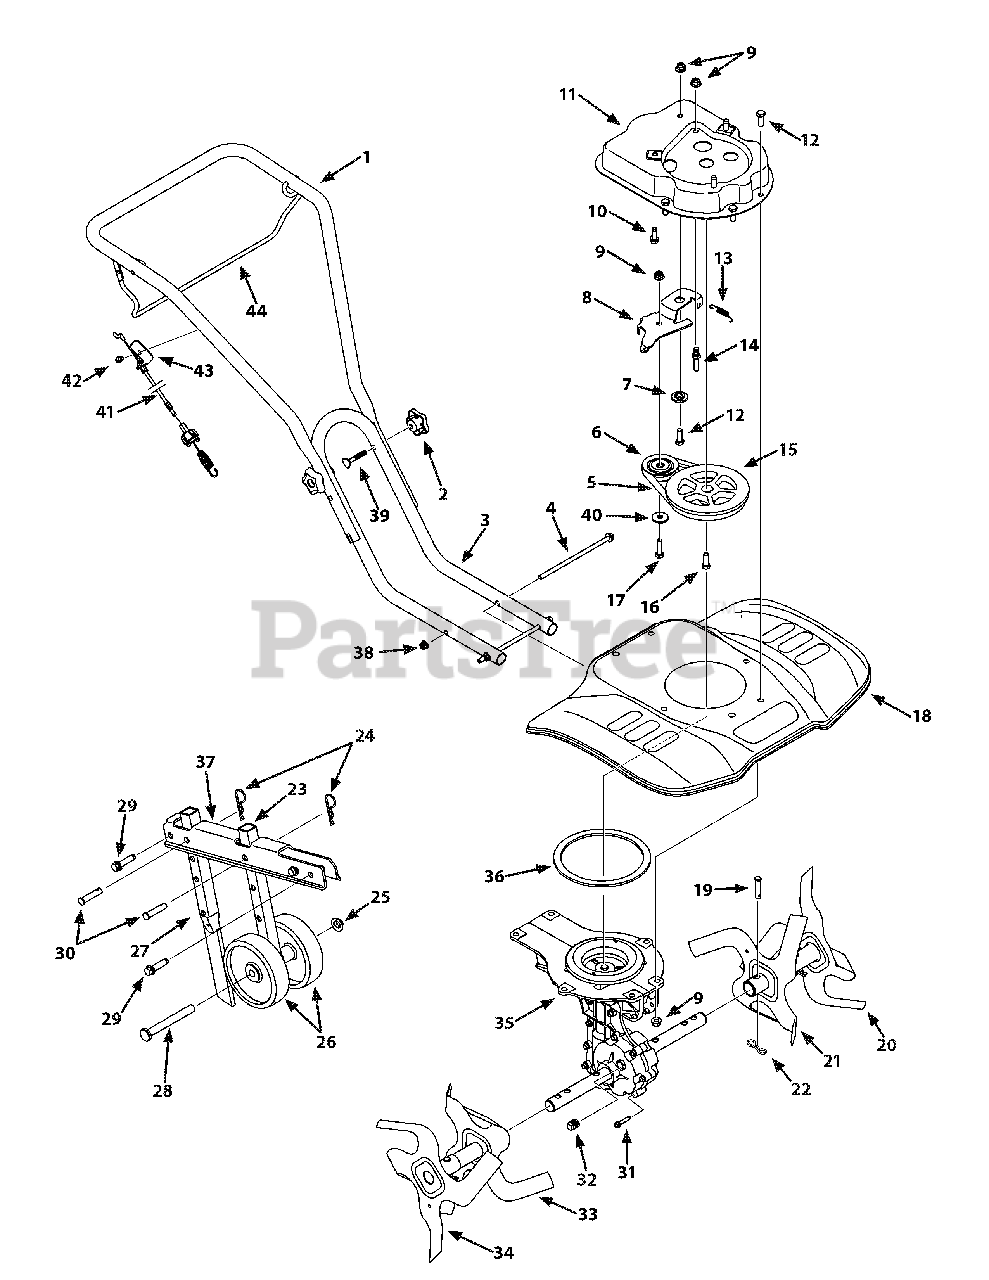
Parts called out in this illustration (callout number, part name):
1	Upper Handle
2	Star Handle Knob
3	Lower Handle
4	Flange Screw: 5/16-18:7.5:GR5
5	V-Belt
6	Idler Pulley
7	Shoulder Spacer
8	Idler Bracket
9	Flange Lock Nut: 3/8-16
10	TT Screw: 3/8-16:1.00
11	Belt Cover
12	HH Cap Screw: 3/8-16:1.00
13	Extension Spring
14	Stud: 33 x 1.5: 3/8-16
15	Flywheel Pulley
16	HH Cap Screw: 3/8-24:1.00
17	HH Cap Screw: 3/8-16:1.55
18	Tine Shield 61 cm
19	Clevis Pin
20	Outer Tine Assembly LH
21	Inner Tine Assembly LH
22	Cotter Pin, Bow Tie
23	Rear Wheel Tube
24	Cotter Pin
25	Push Cap
26	Wheel 5 x 1.38
27	Depth Stake Tube
28	Axle Shaft
29	TT Screw 3/8-16 x 1.50
30	Clevis Pin
31	TT Screw: 1/4-20:1.25
32	Pipe Plug: 1/4-18 NPT
33	Inner Tine Assembly RH
34	Outer Tine Assembly RH
35	Case Assembly
36	Gasket
37	Wheel Bracket
38	Flange Lock Nut: 5/16-18
39	Carriage Bolt
40	Flat Washer, .406 x .875 x .059
41	Clutch Cable
42	TT Screw: 1/4-20:.50
43	Cable Mount Bracket
44	Clutch Bail
